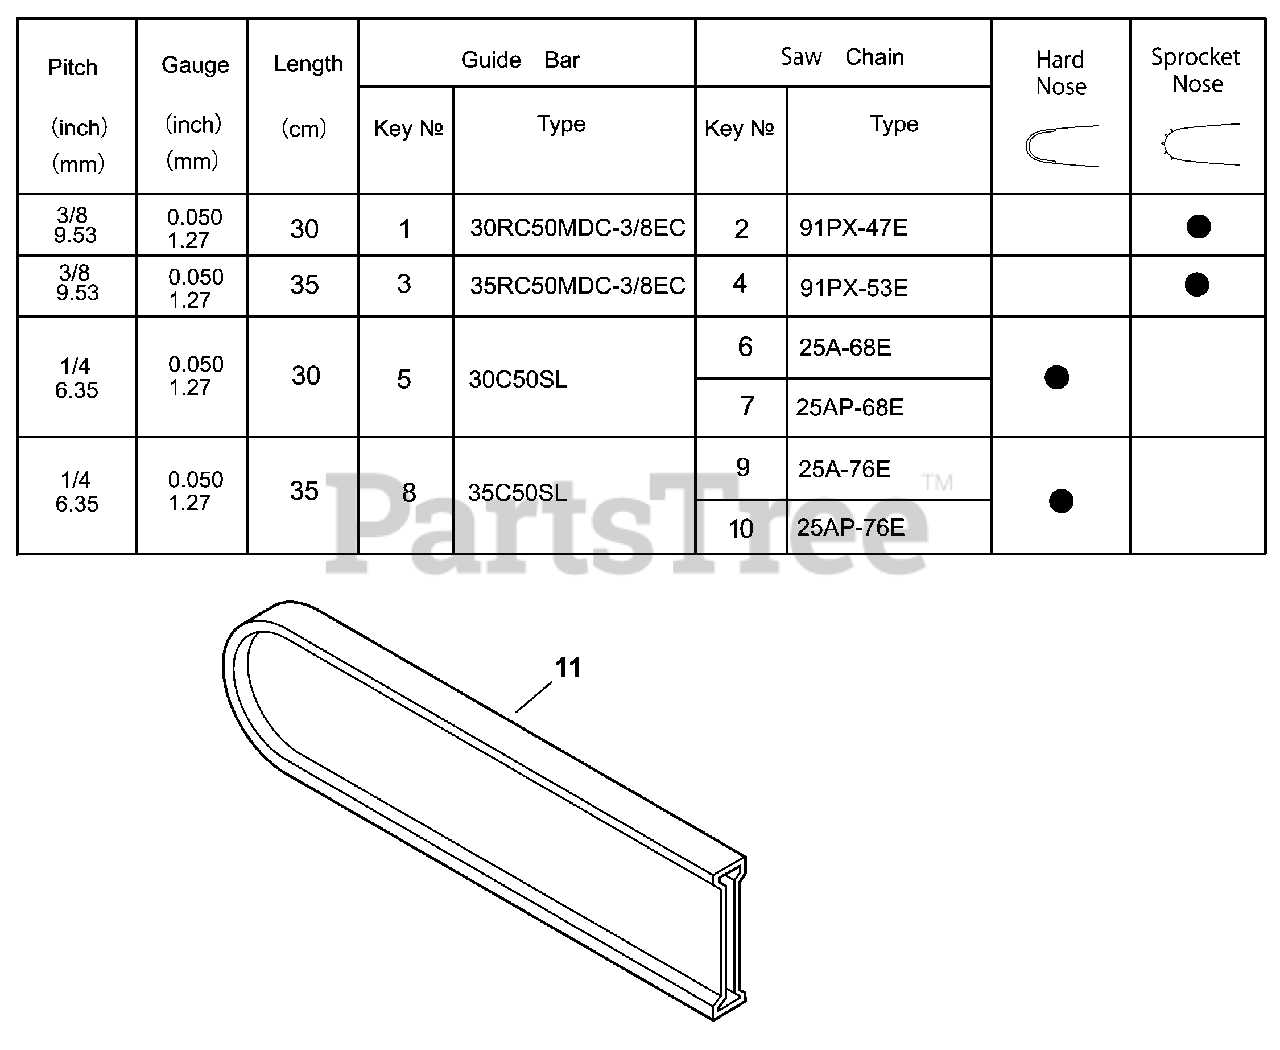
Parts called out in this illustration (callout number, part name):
1	GUIDE BAR - 12"
2	SAW CHAIN - 91PX47E
3	GUIDE BAR, 14"
4	SAW CHAIN - 91PX53E
5	GUIDE BAR - 12" - 30C50SL ECHO
6	SAW CHAIN - 25A-68E
7	SAW CHAIN - 25AP68E
8	GUIDE BAR, 14" - 35C50SL ECHO
9	SAW CHAIN - 25A-76E
10	SAW CHAIN - 25AP76E
11	SCABBARD
